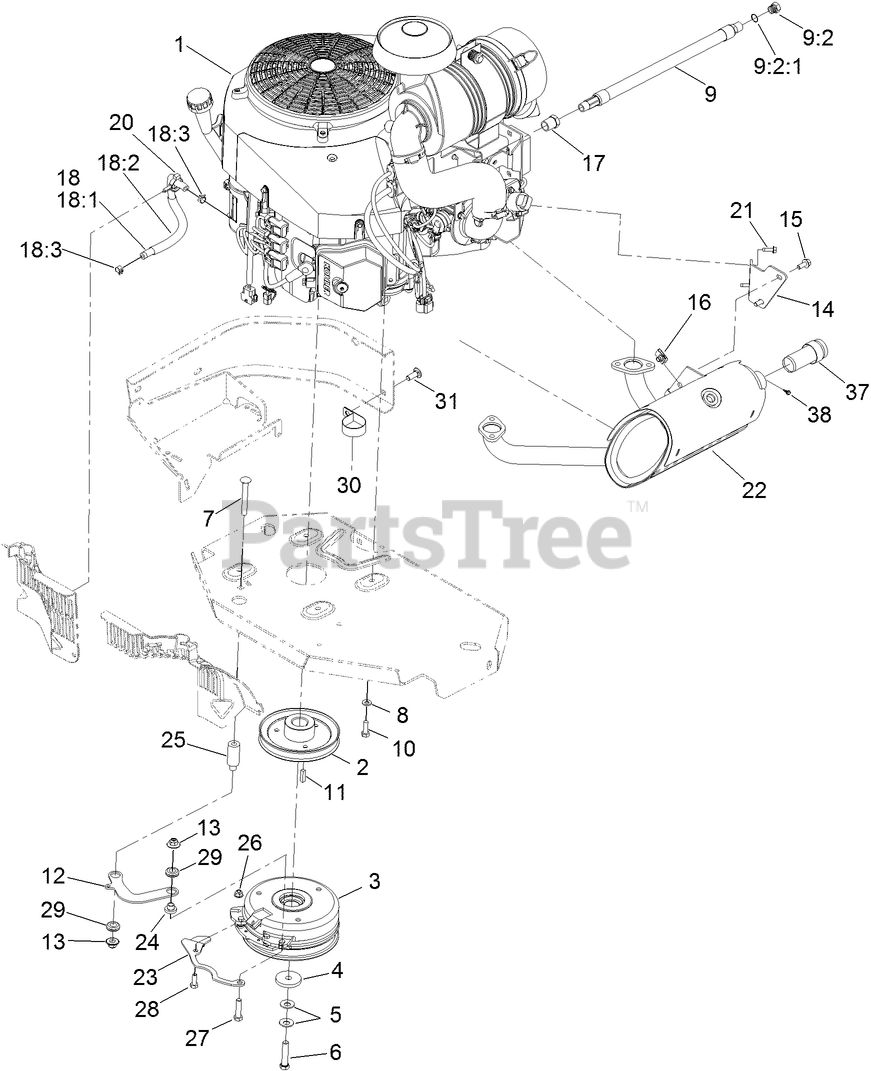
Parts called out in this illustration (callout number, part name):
2	SHEAVE
3	CLUTCH KIT
4	WASHER-CLUTCH
5	WASHER-SPRING
6	SCREW-HH W/LOCTITE
7	SCREW-CARR
8	WASHER-SPRING
9	OIL DRAIN HOSE ASM
9:2	PLUG-HH
9:2:1	O-RING
10	SCREW-HH
12	LINK-ANCHOR, CLUTCH
13	NUT-FLANGE, NI
14	Bracket-Muffler
15	SCREW-HHF
16	NUT-U
17	BUSHING
18	FUEL LINE W/ SLEEVE ASM
18:1	HOSE-FUEL
18:2	SLEEVE-THERMAL
18:3	CLAMP-HOSE
20	CLAMP-HOSE
22	MUFFLER
23	BELT-GUIDE
24	SPACER
25	SPACER
26	NUT-HF, NI
27	SCREW-HH
28	SCREW-HH
29	GROMMET-RUBBER
30	CLAMP-R
31	SCREW-CARR
37	ARRESTOR-SPARK
38	SCREW-HWH
